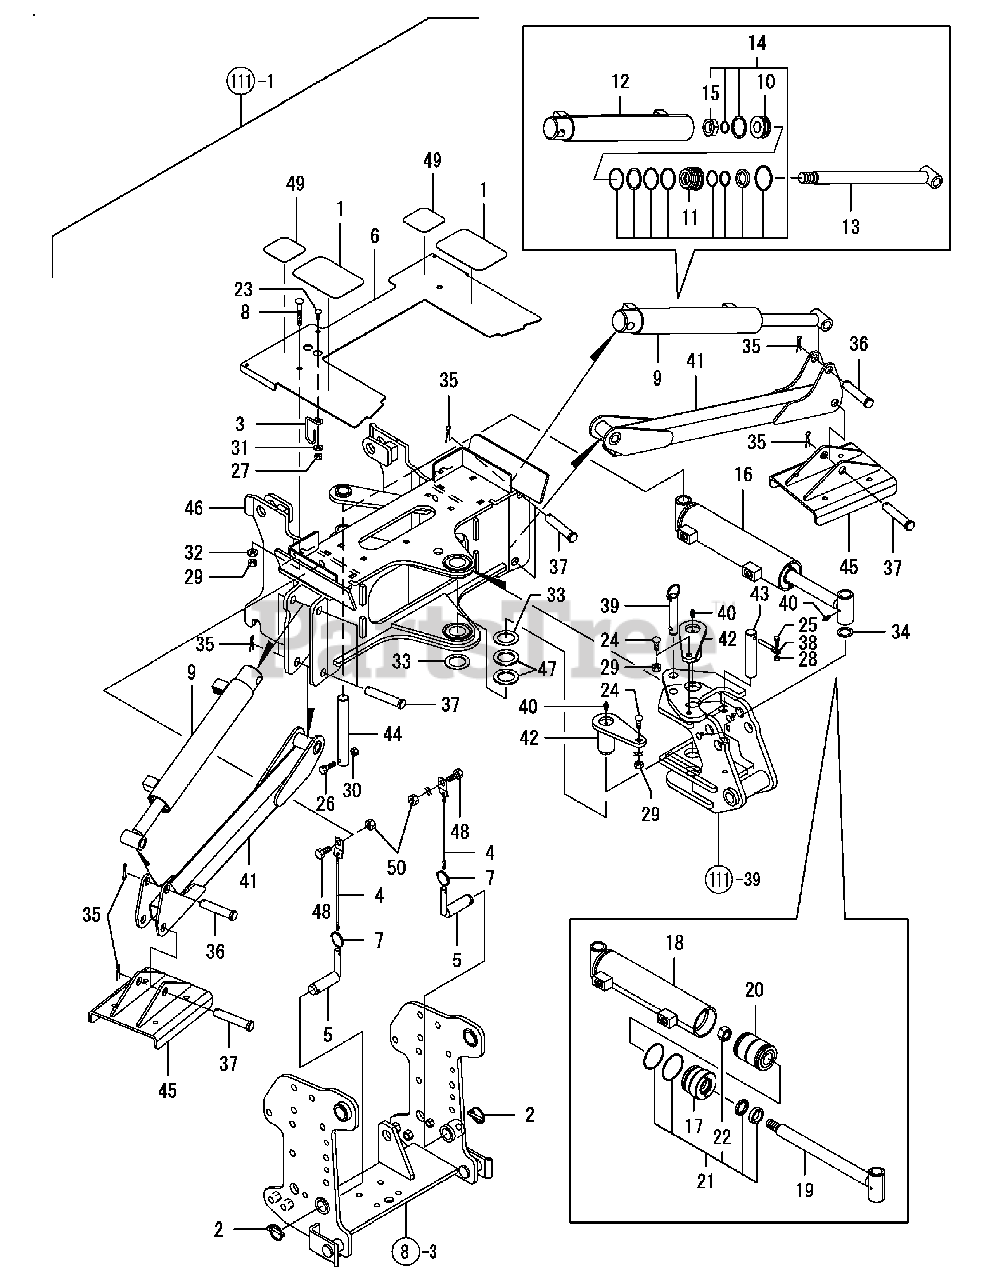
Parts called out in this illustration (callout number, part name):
3	WIRE HOSE RETAINER
4	CABLE ASSEMBLY
8	BOLT, CARRIAGE 3/8
9	CYLINDER, 2X11-1/4
16	CYLINDER, 2-1/2
18	CYLINDER BARREL
21	SEAL REPAIR KIT
23	BOLT, CARR 31X75
24	BOLT, CARR 38X150
25	BOLT, HEX 31X112
26	BOLT, HEX 38X200
27	NUT, LOCK NC 31
28	NUT, LOCK NF 31
29	NUT, LOCK NC 38
30	NUT, LOCK NF 38
31	FLAT, LOCK 5/16
33	MACH BUSH, 225
34	MACH BUSH, 150
35	PIN, COTTER 19X125
36	CLEVIS PIN, 3-1/4
40	GREASE, FITTING
41	STABILIZER LEG
45	STABILIZER PAD
48	HEX HEAD CAP SCREW
